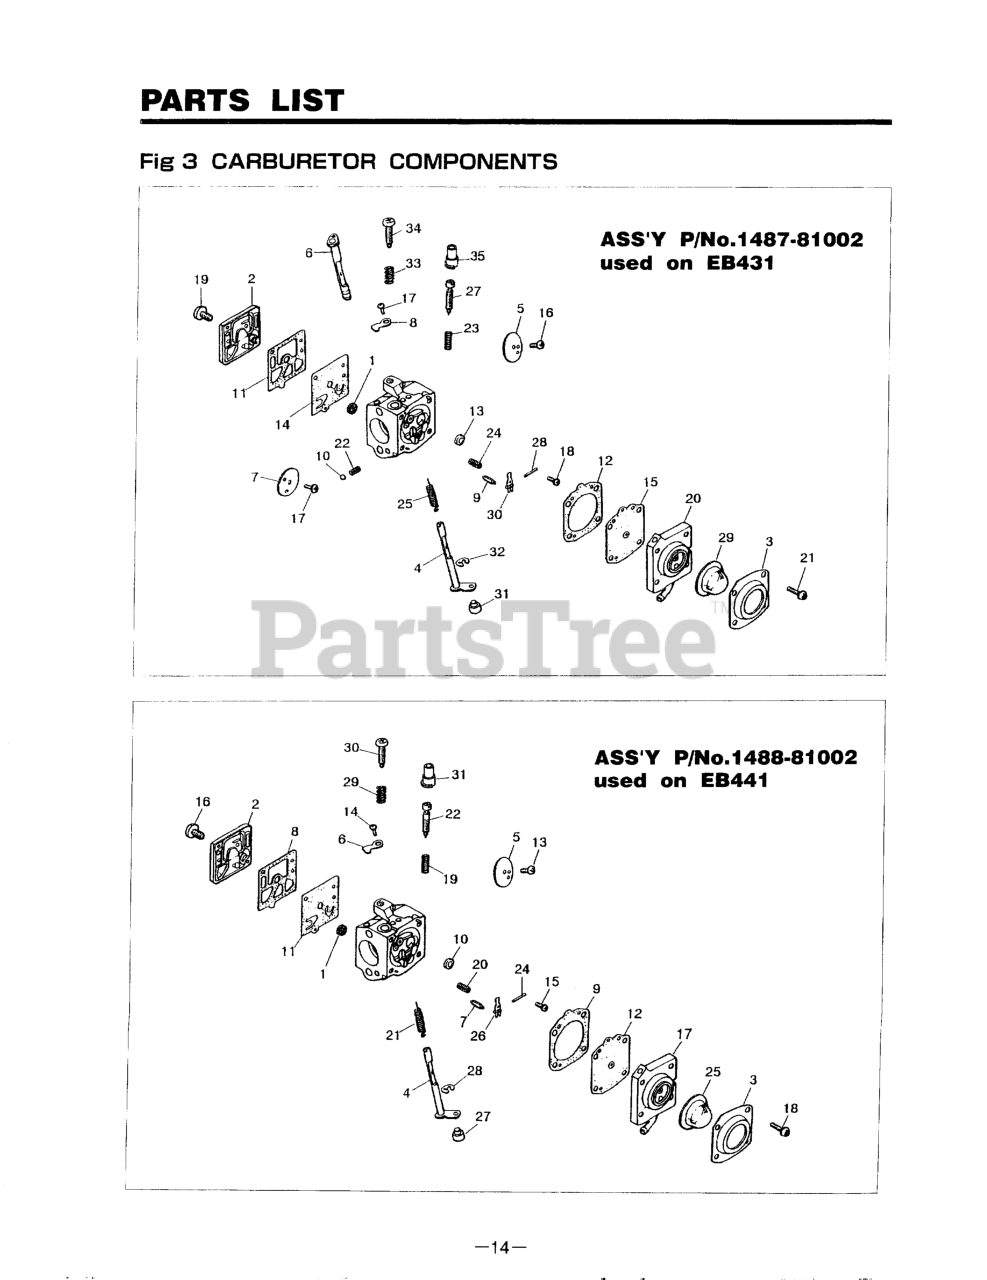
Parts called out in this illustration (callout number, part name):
2	COVER, PUMP
3	COVER, PUMP
4	SHAFT ASSEMBLY
5	VALVE, THROTTLE
6	THROTTLE STOP
7	VALVE, INLET
8	KIT ONLY
9	KIT ONLY
10	PLUG, WELSH
11	KIT ONLY
17	BODY ASSY (RPLS 1491-81490)
18	SCREW (REPLACES 1491-81350)
20	KIT ONLY
21	SPRING
22	NEEDLE (H)
24	PIN, METERING LEVER
25	PUMP, PRIMER
26	KIT ONLY
27	SWIVEL (USE -06040)
29	SPRING, IDLE
NI	REBUILD KIT, EB430/440
NI	EB430/40 DIA/GASK KIT
